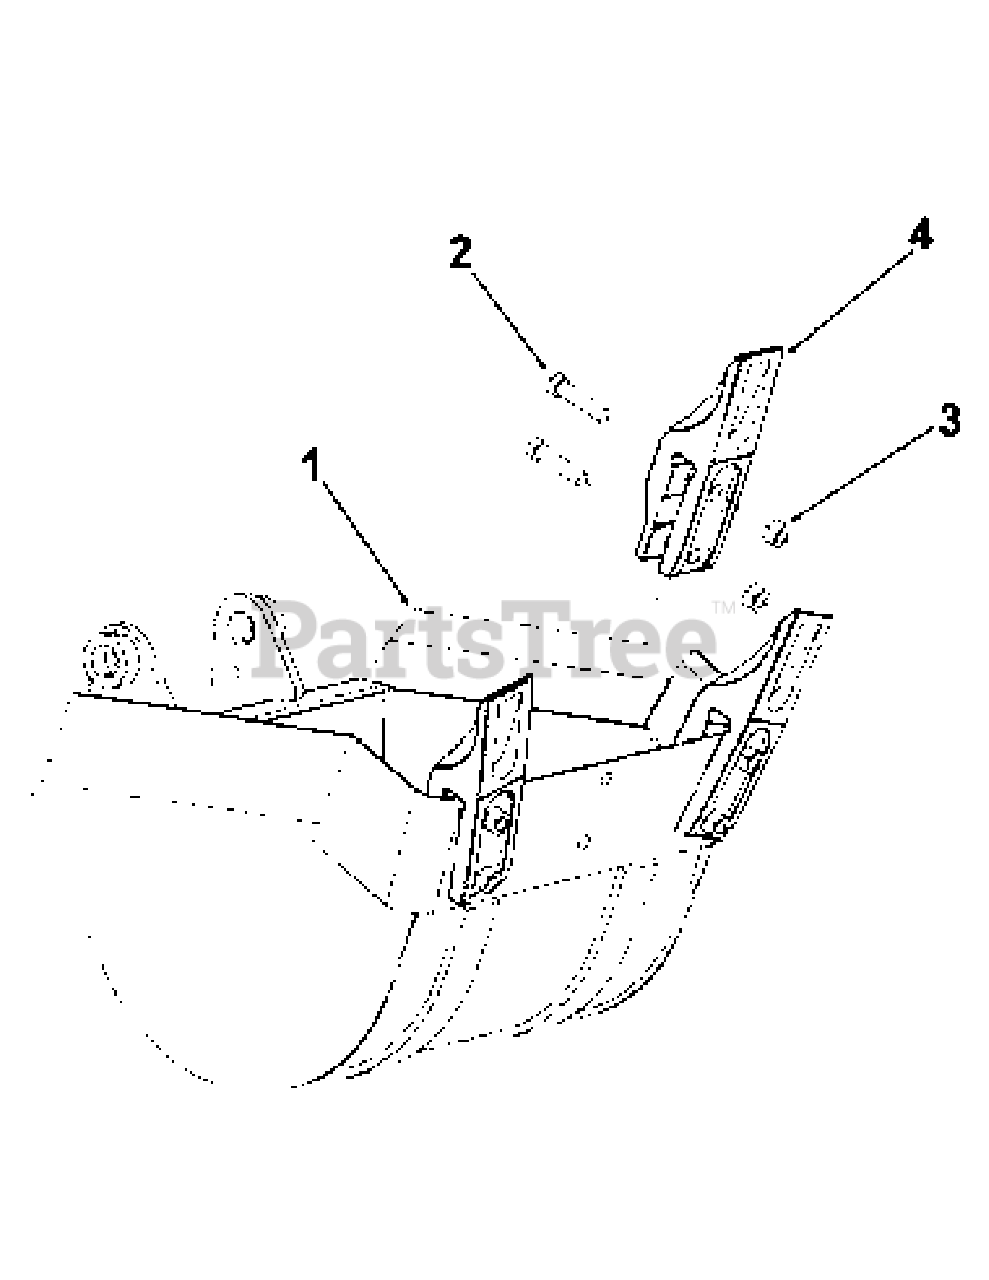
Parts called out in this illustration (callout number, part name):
1	Heavy Duty Bucket - 9"
1	Heavy Duty Bucket - 13"
1	Heavy Duty Bucket - 16"
1	Heavy Duty Bucket - 20"
1	Heavy Duty Bucket - 24"
2	Bolt, 7/16 NF x 1-3/4 Gr 5
3	Locknut, 7/16 NF
4	Tooth Point
